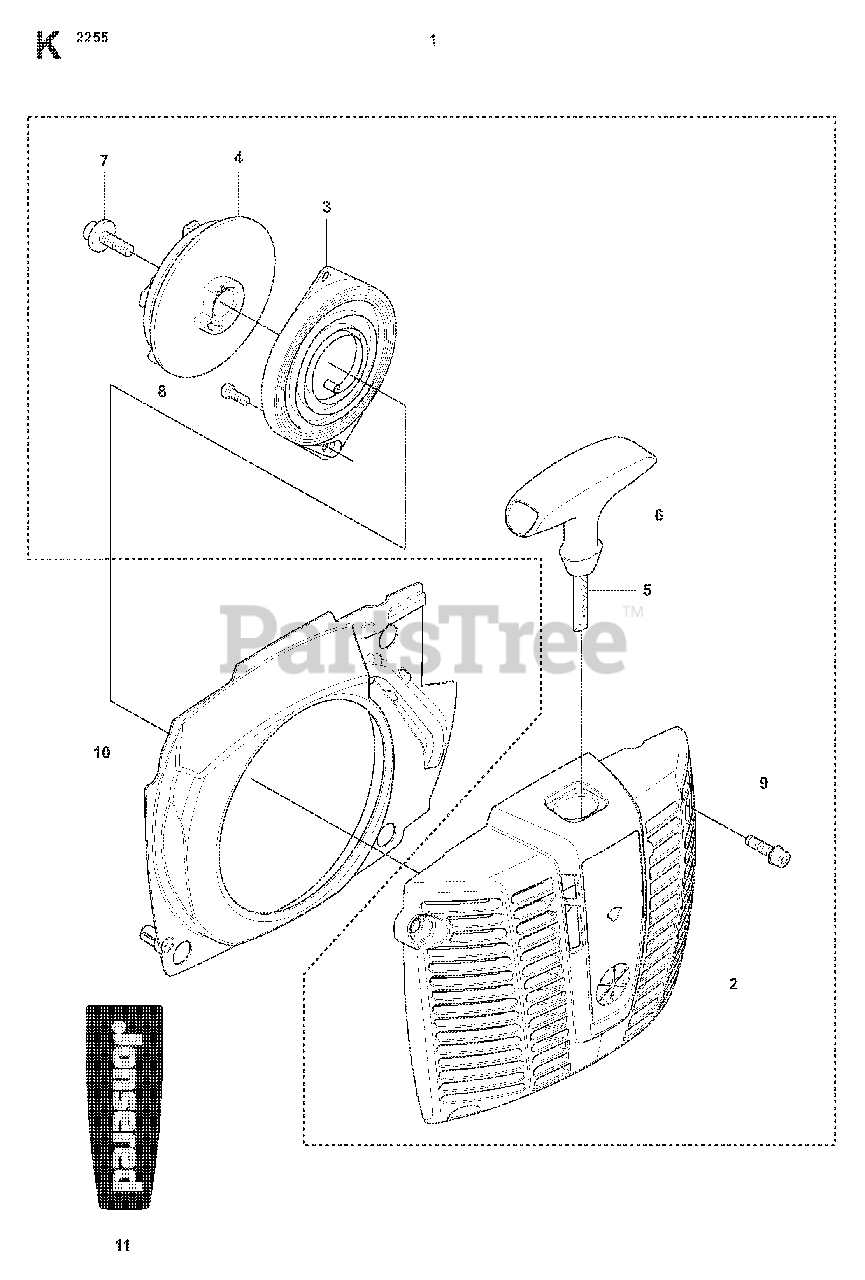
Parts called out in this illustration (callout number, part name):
3	RECOIL SPRING
4	STARTER PULLEY
5	STARTER ROPE
6	STARTER HANDLE
